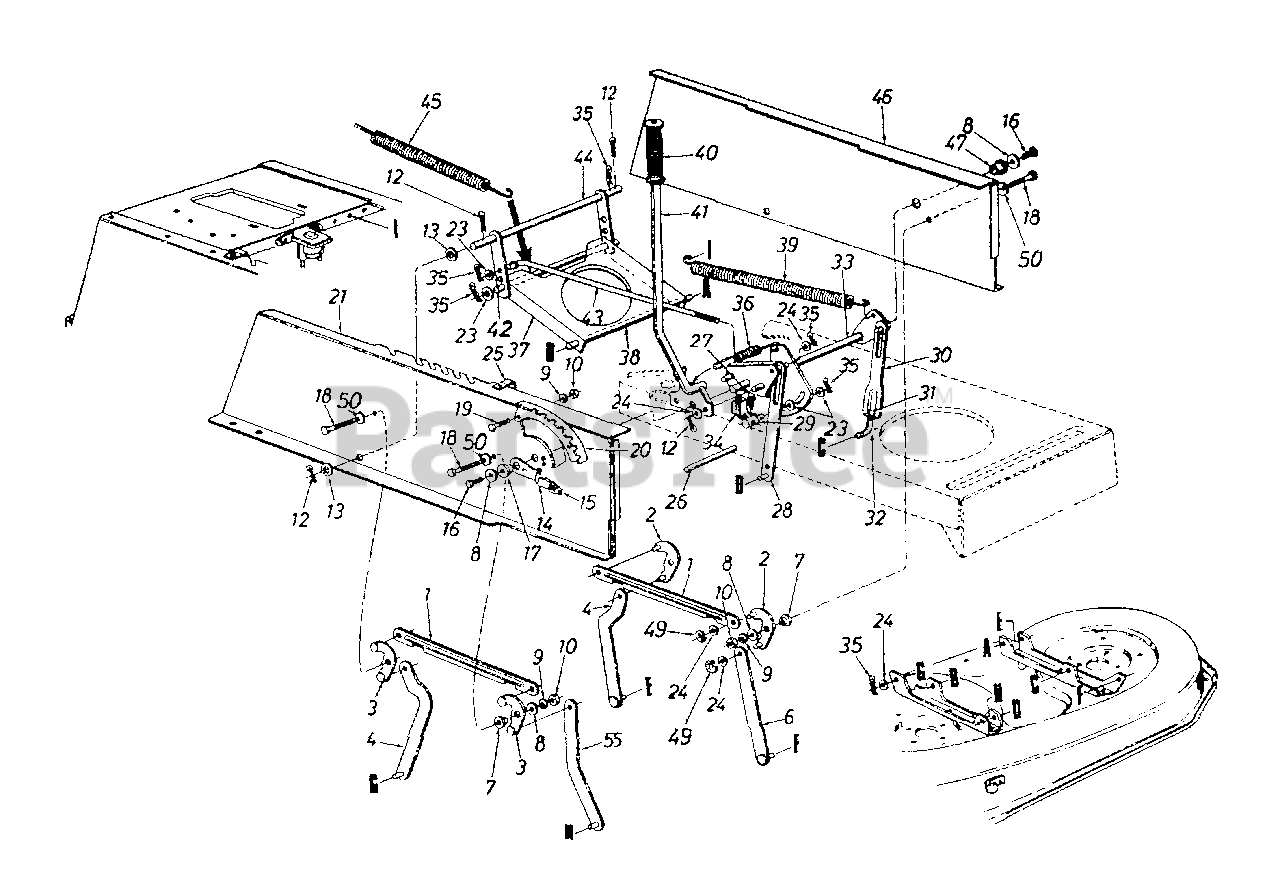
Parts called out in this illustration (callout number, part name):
3	Pivot Link Assembly.- RH
7	Shld. Spacer .318" I.D.
8	Flat Washer .344" I.D. x 1.125" O.D.
9	Lock Washer 5/16" I.D.
10	Hex Nut 5/16-18 Thd.
12	Cotter Pin 1/8" Dia.
13	Flat Washer .635" I.D. x 1.0" O.D.
14	Hgt Adj. Stop Lever Assembly
15	Knob
16	Hex Wash. TT-Tap Scr. 5/16-18 x .625"
17	Flange Bearing .63" I.D.
18	Hex Wash. Hd. Scr. 5/16-18 x .875"
19	Hex Bolt 5/16-18 x .75" Lg.
20	Index Brkt.
24	Flat Washer .531" I.D. x .93" O.D.
25	Clamp
26	Running Board Rod
27	Hex Wash. Hd. Tap Scr.
31	Hex Nut 1/2-20 Thd.
32	Lift Link Adjuster
35	Inter. Cotter Pin 3/8" Dia.
36	Extension Spring
39	Extension Spring
40	Grip (Lift Handle)
43	Disengagement Rod
49	"E"-Ring
50	Washer .325" I.D.
